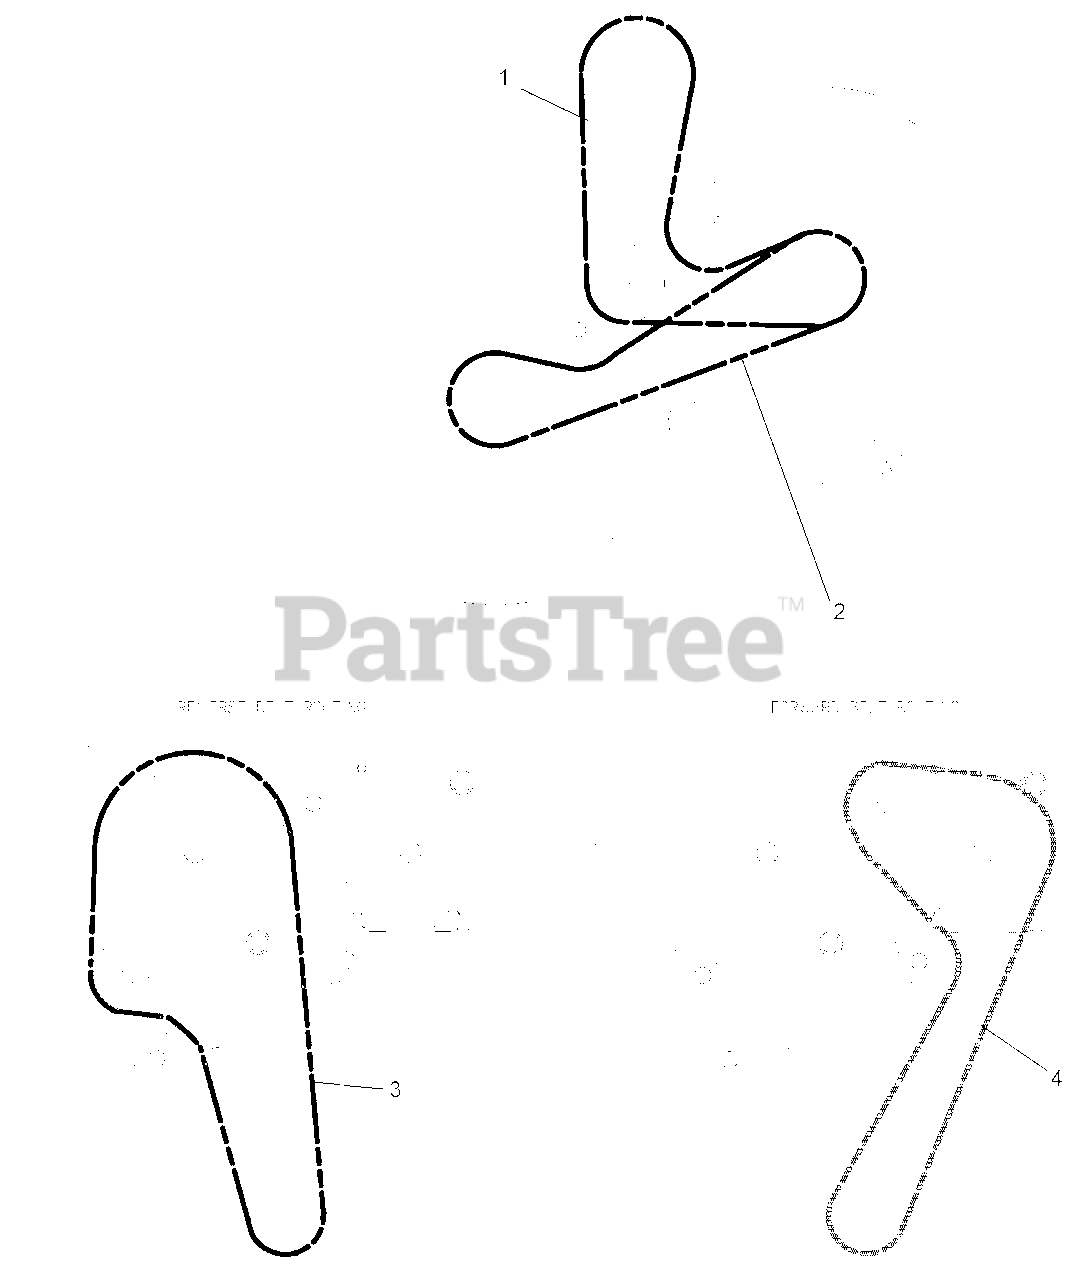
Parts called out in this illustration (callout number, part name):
1	Belt, HA 56.95 Wrapped
2	Belt, HA 51.20 Wrapped
3	Belt, 3L Clutching Cover
4	Belt, 3L Clutching Cover
